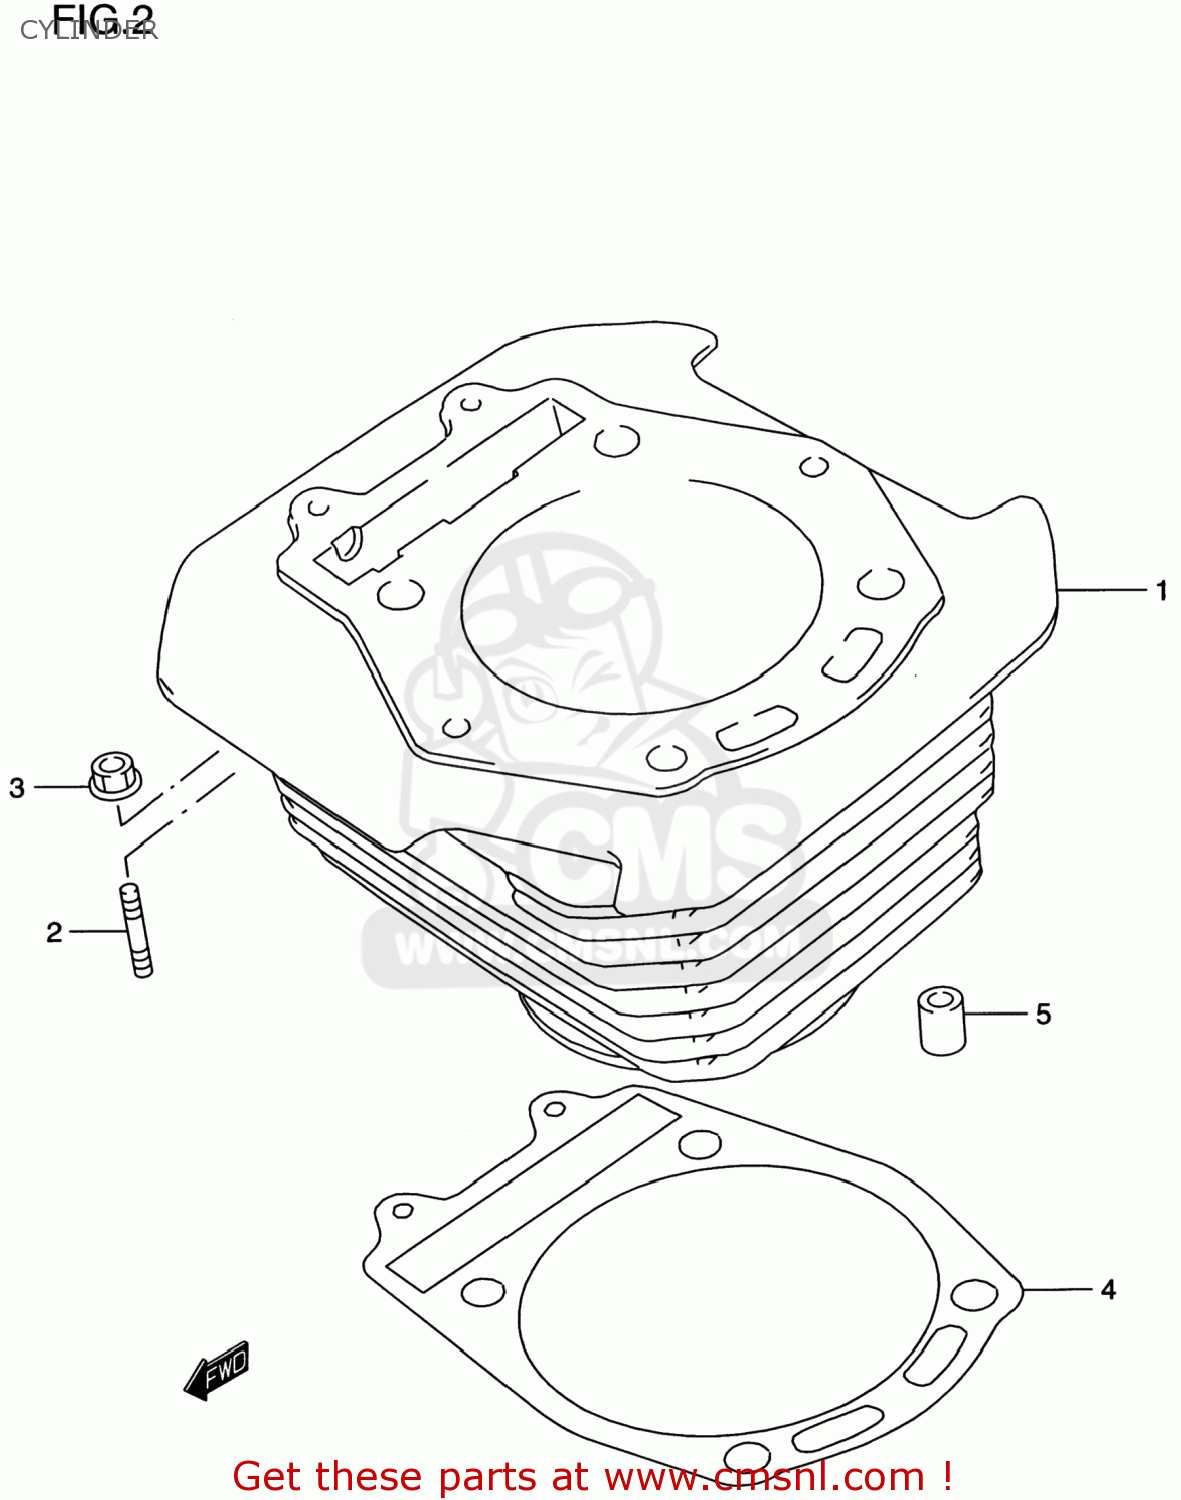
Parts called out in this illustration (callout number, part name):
1	CYLINDER
2	STUD 6X20
3	NUT
4	GASKET,CYLINDER
5	PIN
